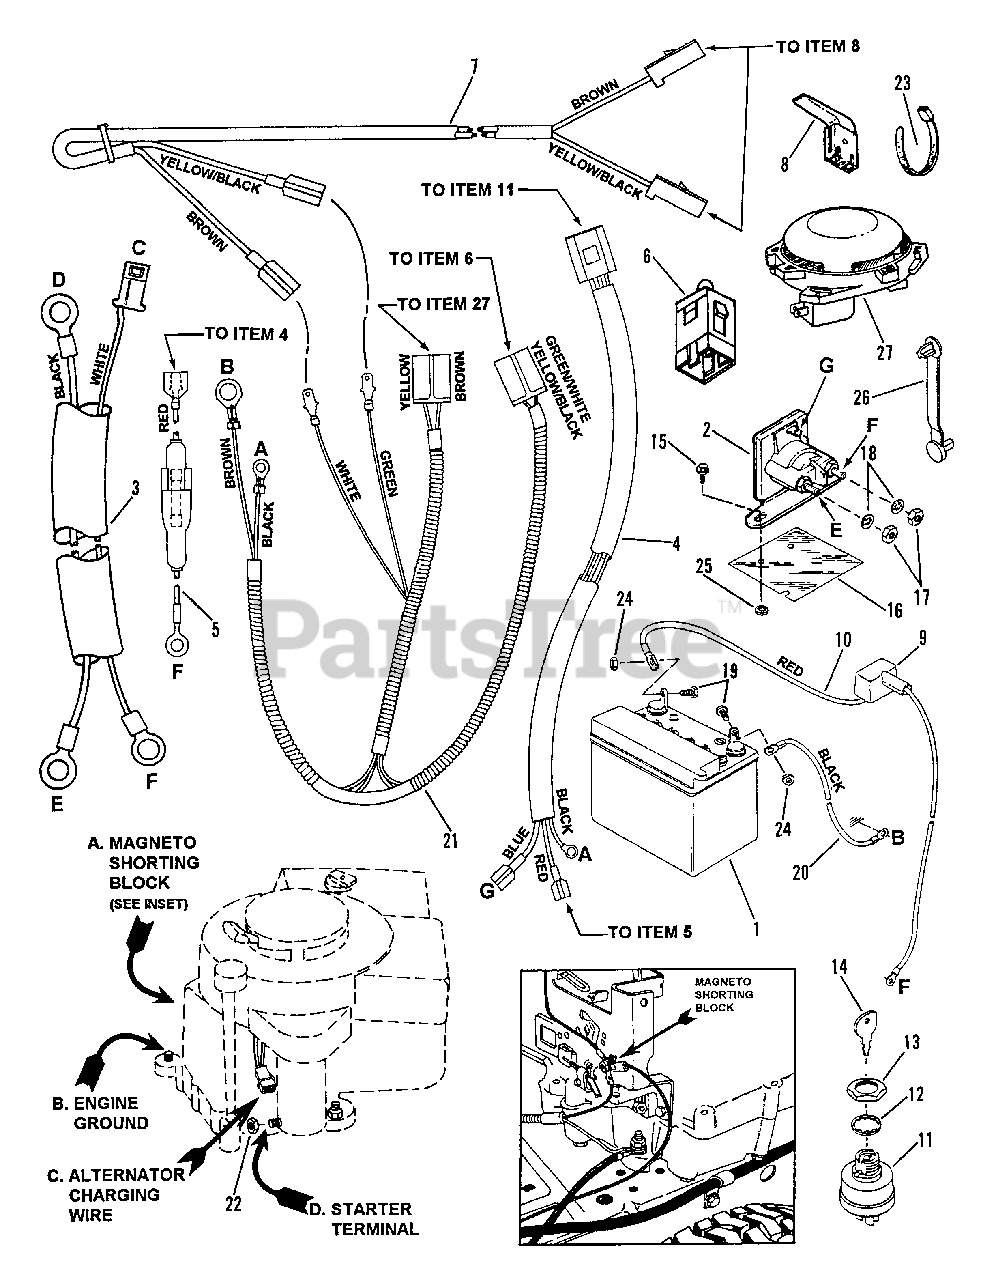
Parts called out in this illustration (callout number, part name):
1	KIT, 12V Dry Charge Battery
2	SOLENOID
3	HARNESS, Starter Wiring
4	HARNESS, Ignition Wiring
5	HOLDER, Fuse
6	SWITCH, Traction Operator's Presence
7	HARNESS, (Deck Interlock Wiring)
8	SWITCH, Deck Interlock
9	COVER, Battery Cable
10	CABLE, Positive (Red)
11	SWITCH, Ignition (Includes keys #11138)
12	WASHER, 5/8 Internal Tooth Lock
13	NUT, 5/8-32 Hex
14	KEY, Switch
15	SCREW, 1/4-20 x 1/2" Self-Tapping
16	PROTECTOR, Solenoid
17	NUT, 1/4-20 Hex
18	WASHER, 1/4 Internal Tooth Lock
19	SCREW, 1/4-20 x 5/8" Hex Head Cap
20	CABLE, Negative
21	HARNESS, Operator Presence Control Wire
22	NUT, 1/4-20 Hex
23	TIE, 7" Long Cable
24	NUT, 1/4-20 Hex Lock
25	RETAINER, 1/4 Bolt
26	TIE, 2" Long Cable
27	SWITCH, Seat
